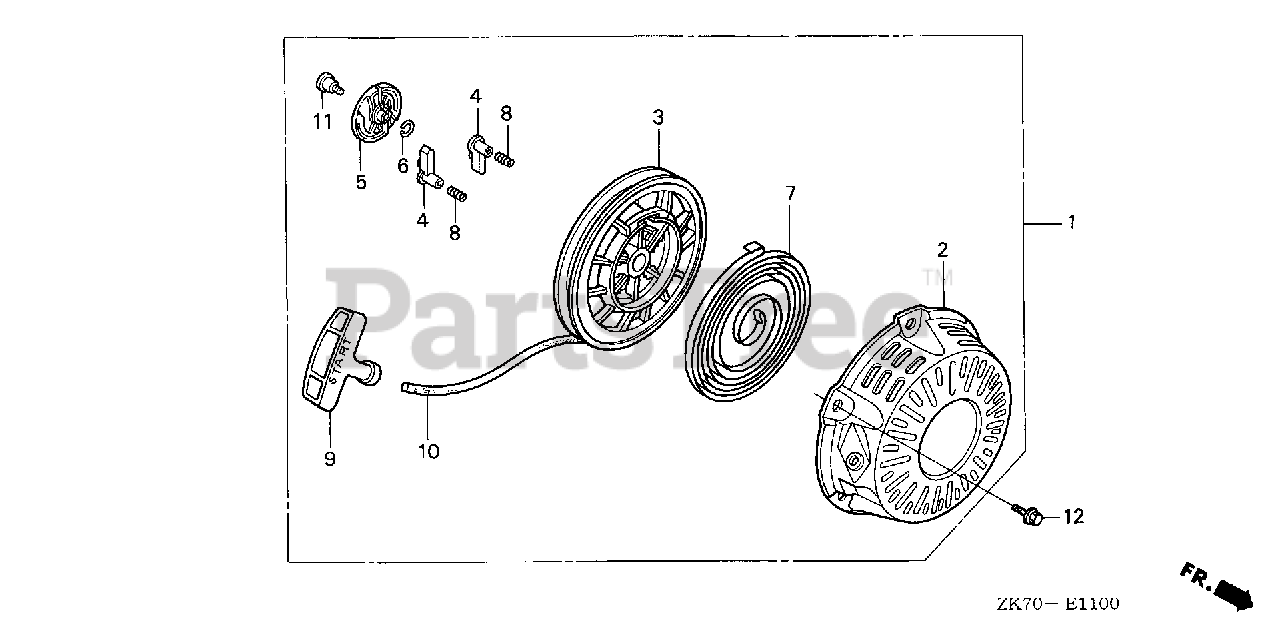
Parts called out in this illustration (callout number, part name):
1	STARTER ASSY., RECOIL *R280* (POWER RED)
2	CASE, RECOIL STARTER *R280* (Honda Code 7346836). (POWER RED)
3	REEL, RECOIL STARTER (NATURAL) (ENGINE NO.)
4	RATCHET, STARTER
5	GUIDE, RATCHET (ENGINE NO.)
6	SPRING, FRICTION (ENGINE NO.)
7	SPRING, RECOIL STARTER
8	SPRING, RETURN (ENGINE NO.)
9	GRIP, STARTER
10	ROPE, RECOIL STARTER (#5X55")
11	SCREW, SETTING (ENGINE NO.)
12	BOLT, FLANGE (6X10)
